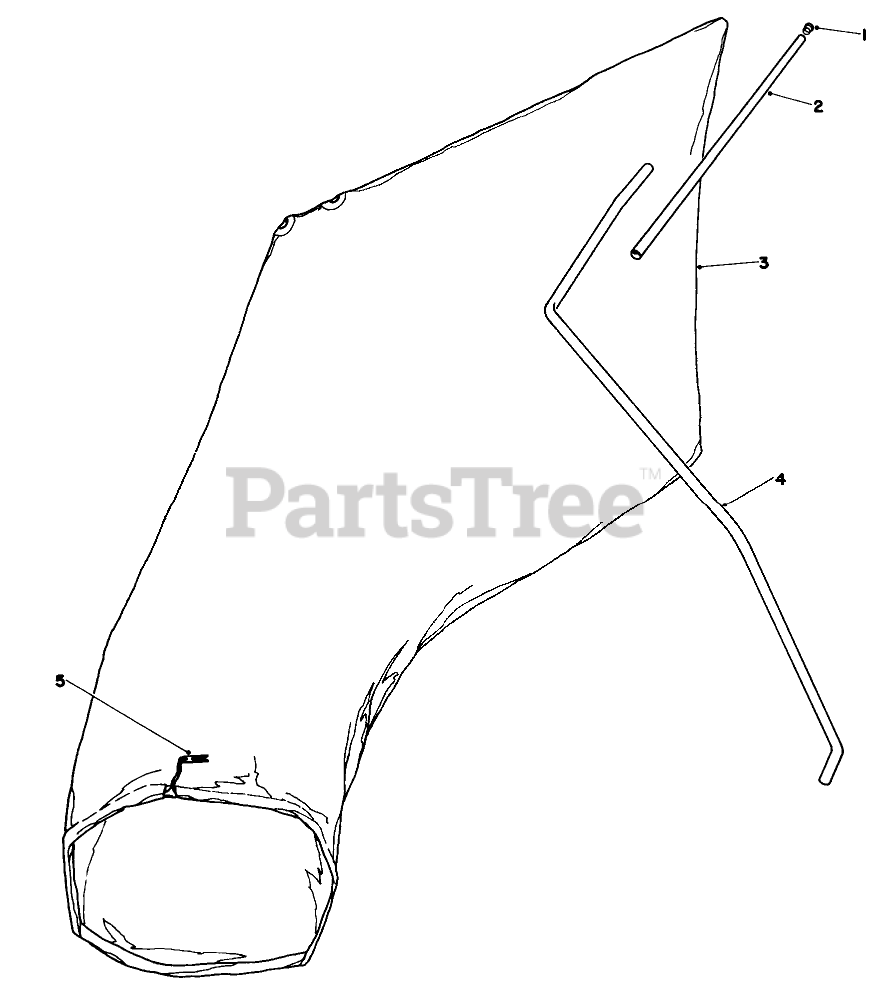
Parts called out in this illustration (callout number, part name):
2	BAG HANGER TUBE
3	Bag (Incl. Ref. #5)
4	HANGER ROD
5	BAG CORD FASTENER
